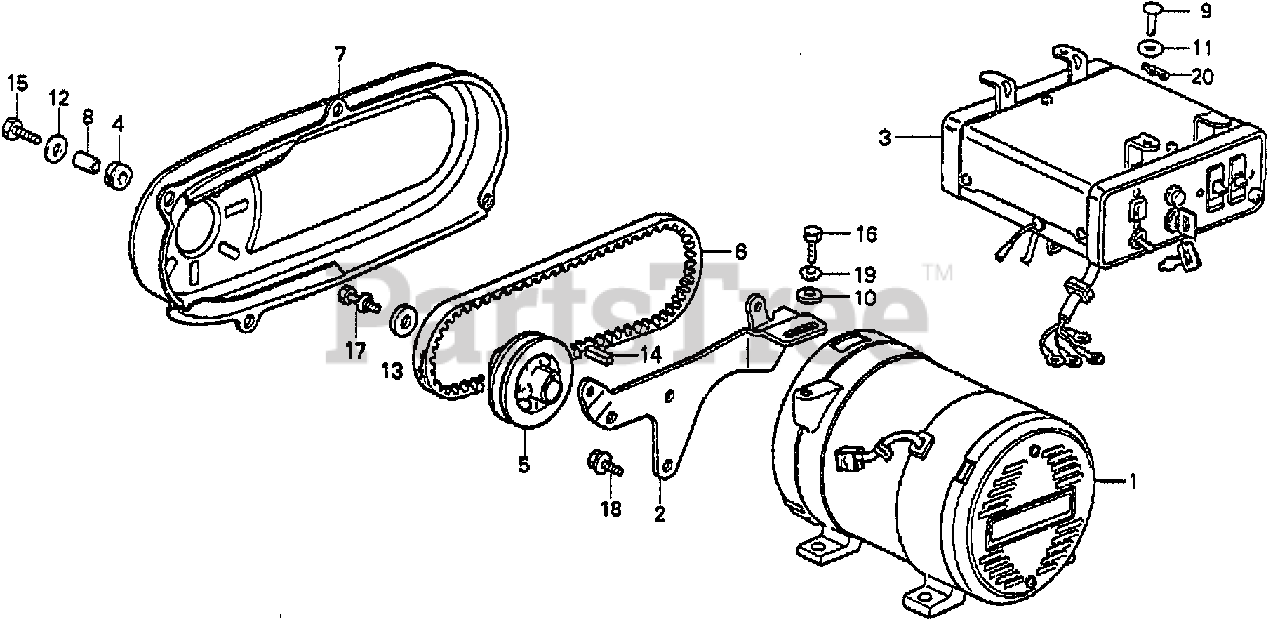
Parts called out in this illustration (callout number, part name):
1	GENERATOR ASSY. *R8/NH31/NH1* (BRIGHT RED/MC KINLEY WHITE/ BLACK)
2	STAY, GENERATOR
3	BOX ASSY., CONTROL
4	GROMMET, WIRE HARNESS
5	V-PULLEY (60)
6	V-BELT (B-37) (NOT AVAILABLE)
7	COVER, BELT *R8* (BRIGHT RED) (NOT AVAILABLE)
8	COLLAR (8MM)
9	PIN, CONTROL BOX SETTING
10	WASHER (10X30X3.5T)
11	WASHER, FLAT (20MM)
12	WASHER B, HANDLE HOLDER SETTING
13	WASHER, LOCK (8MM)
14	KEY (7X7X33) (YELLOW)
15	BOLT, HEX. (6X16)
16	BOLT, HEX. (10X25)
17	BOLT-WASHER (8X30) (SOURCE: VINTAGE PARTS INC.)
18	BOLT-WASHER (8X20)
19	WASHER, PLAIN (10MM)
20	PIN, LOCK (8MM)
